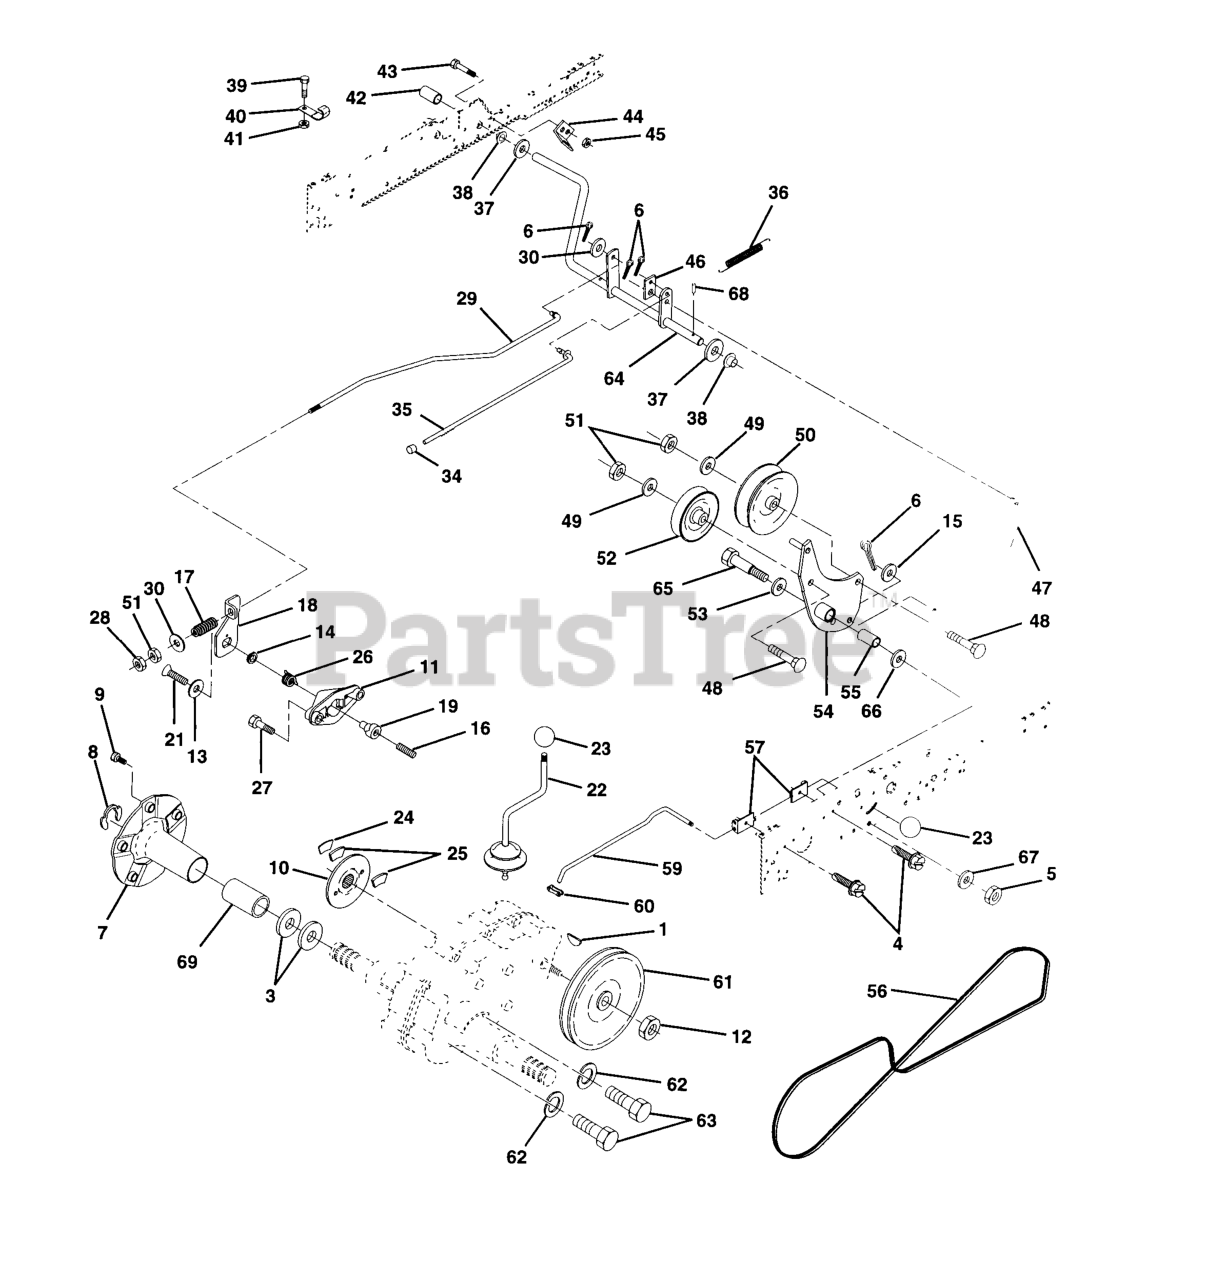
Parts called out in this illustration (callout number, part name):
1	KEY
4	Screw Thdrol 5/16-18 x 1/2 TYT
6	COTTER PIN
7	HUB.WHL.ASM.REAR
9	HUB BOLT
10	DISC BRAKE
11	YOKE-BRAKE DISC
15	WASHER
17	SPRING,ROD BRAKE
18	BRAKE LEVER
19	BRAKE DISC CAM
21	Screw Flat Head 1/4-28 x 3/4
22	GEAR SHFT LVR T
24	BRAKE PUCK SUPPORT
25	BRAKE PUCK TOP
26	RETURN SPRING
27	SCREW
28	NUT
29	ROD BRAKE ZINC GT
30	WASHER
34	PLUNGER CAP
35	PARKING BRAKE ROD
36	SPRING DRIVE GROUND
39	Screw Fin #10-24 x 1
40	ACT-SWITCH T
41	LOCKNUT
42	COVER, PEDAL (1 2)
43	BOLT.HEX.1/4.X.3/4.DICHROMATE
44	BRKT SWITCH GT
45	LOCKNUT.NYLOC.1/4-20
46	RETAINER SPRING
47	CLUTCH ROD
49	Washer 13/32 x 7/8 x 13 Ga
50	FLAT IDLER PULLEY
51	NUT
52	PULLEY.IDLER.V.
54	CLUTCH ARM ASSY
55	BEARING LT (2 2)
56	V-BELT GROUND DRIVE
57	BRACKET SHIFT ROD
59	ROD SHIFT HI LO
60	CONNECTING LINK
61	TRANSAXLE PULLEY
62	LOCKWASHER
63	BOLT
64	PEDAL SHAFT
66	WASHER.BLADE
67	WASHER
68	ROLL PIN STD
69	COVER.HUB.BLACK
